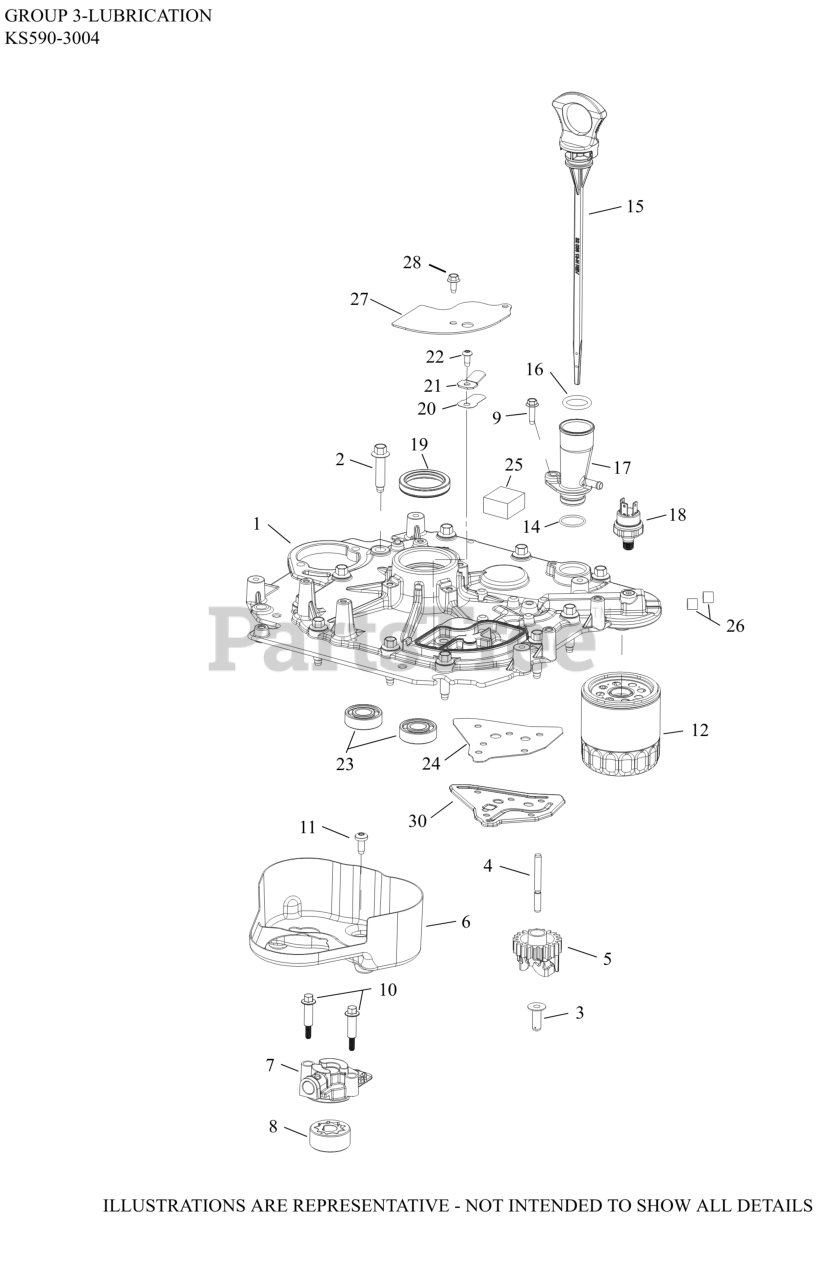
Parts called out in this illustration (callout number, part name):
1	PLATE, CLOSURE ASSY
2	SCREW, HEX FLANGE
3	PIN, GOVERNOR REGULATING
4	SHAFT, GOVERNOR CROSS
5	KIT, GOVERNOR GEAR
6	BAFFLE, OIL
7	HOUSING, OIL PUMP ASSY
8	PUMP ASSY, OIL
9	SCREW, THD FRM-USE 25 086 473-S
10	SCREW, SHOULDER THREAD FORMING
11	SCREW, THREAD FORMING
12	OIL FILTER
15	DIPSTICK, ASSY
17	TUBE, DIPSTICK ASSY
18	SENSOR, OIL PSI 3 TERMINAL
19	SEAL, OIL
20	REED, BREATHER
22	SCREW, BUTTON HEAD (M5 X 12)
23	BEARING, BALANCE SHAFT
26	PLUG, CTSK PIPE 1/8"
27	COVER, BREATHER
28	SCREW, FLG THD FRM M5X0.8X13
NI	PLATE, CLOSURE ASSEMBLY
NI	RETAINER, REED
NI	FILTER, BREATHER
NI	COVER, OIL PASSAGE
